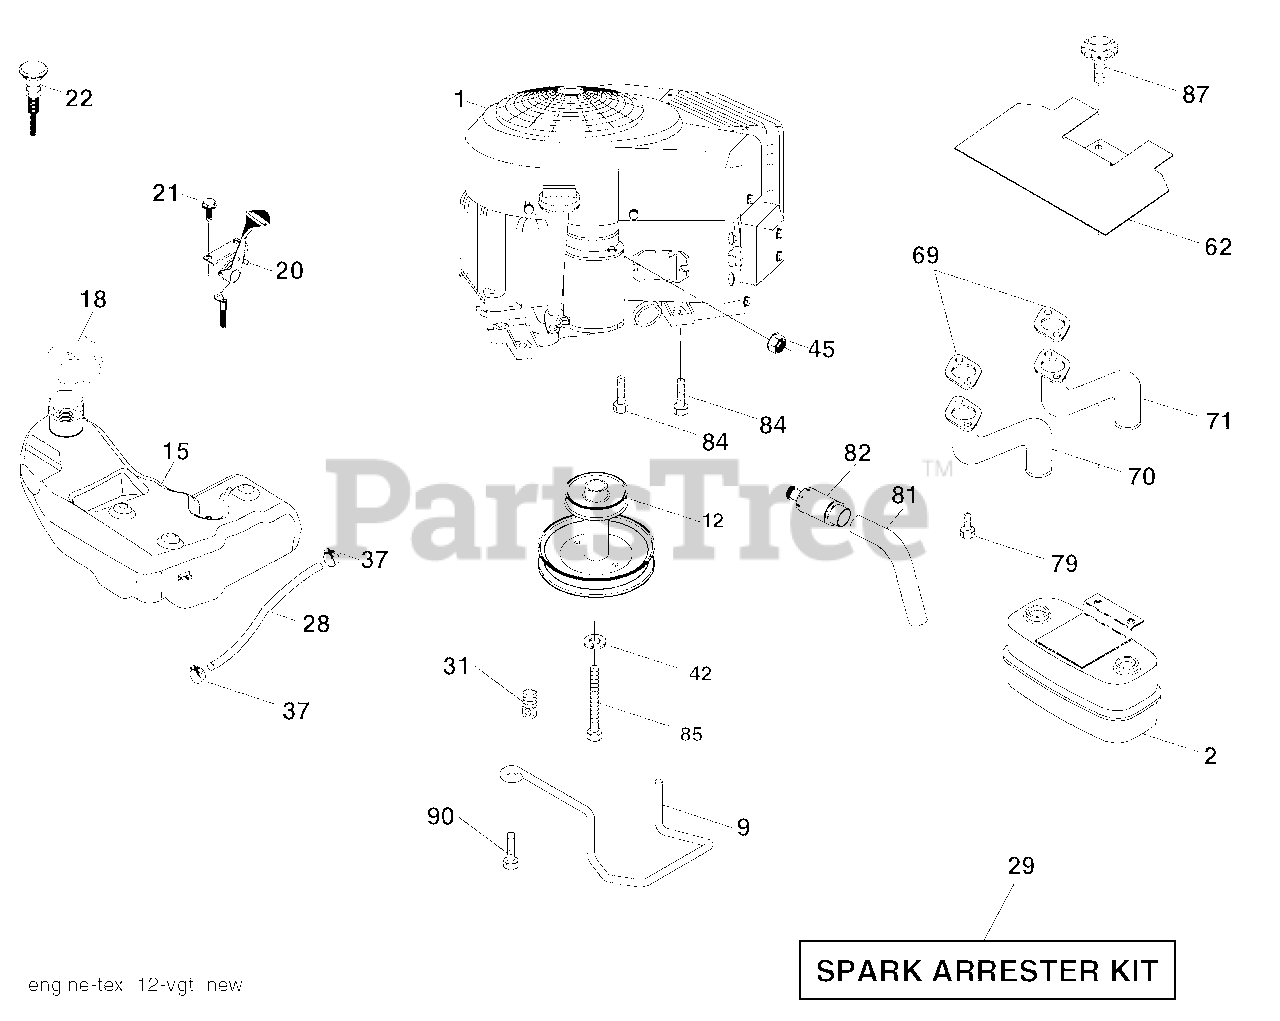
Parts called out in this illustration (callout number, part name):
2	Muffl er
9	Keeper Belt Engine
12	Pulley Engine
15	Tank Fuel 3.0
18	Cap Asm
20	Control Throttle
21	Screw 10 x 3/4 Single Lead-Hex
22	Control Choke
28	Fuel Line
29	Spark Arrester Kit
37	Clamp Hose
42	Washer Lock 7/16
45	Nut Keps Hex 1/4-20 unc
62	Shield Heat Muffl er
69	Gasket
70	Exhaust Tube RH
71	Exhaust Tube LH
79	Screw Socket Head 5/16-18 x 1
81	Tube Drain Oil Easy
82	Plug Drain Oil
84	Screw 3/8-16 x 1-1/4
85	Bolt Hex 7/16-20 x 4 x 5 Ga.-1.5
87	Bolt 5/16-18 x 3/4
90	Screw 3/8-16 x 1
